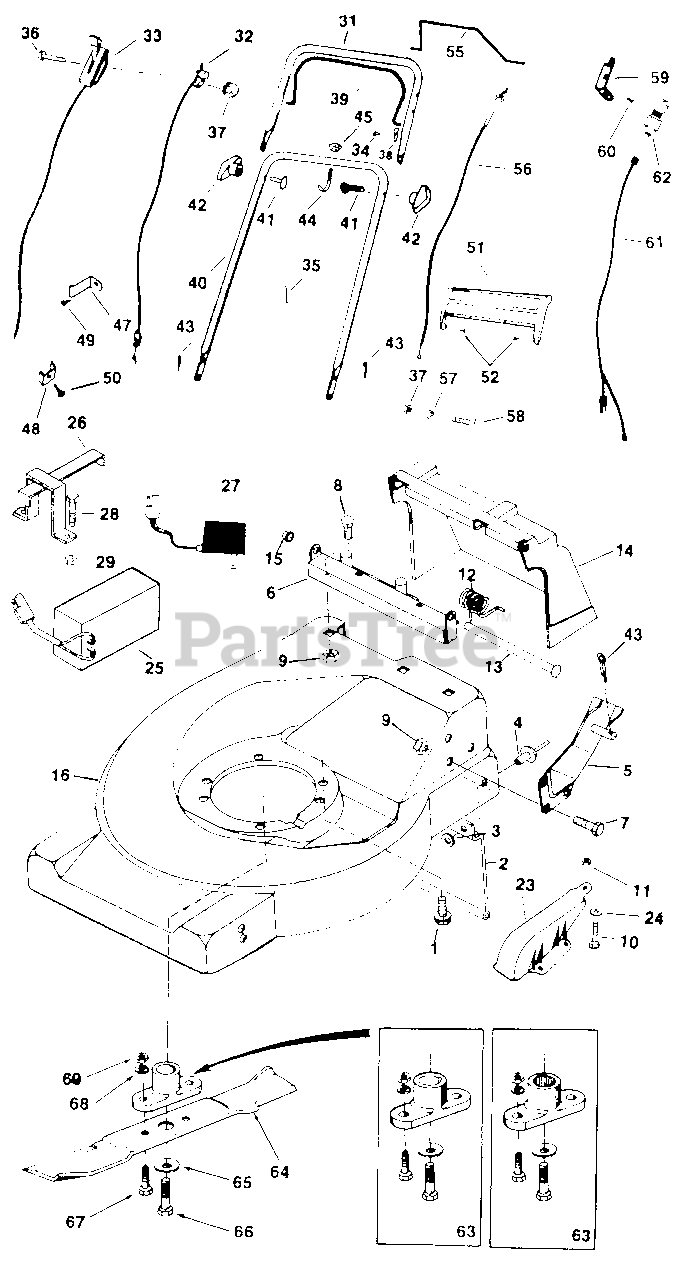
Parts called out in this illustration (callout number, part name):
1	Engine Mounting BoH
2	Trail Shield
3	Fl-Wash. 3/16"1. D.
4	Blind Rivet
5	Handle Bracket
6	Mount Bracket - Grass Catcher
7	Hex Bolt 5/16-18 x 5/8" Lg.
8	Carriage Bolt 5/16-18 x 3/4" Lg.
9	Hex Keps Nut 5/16-18 Thd.
10	Carriage Bolt 1/4-20 x 5/8" Lg.
11	Hex L-Nut 1/4-20 Thd.
12	Spring - Rear Door
13	Hinge Pin - Rear Door
15	Retainer
16	21" Deck Ass'y.
23	Belt Cover
24	Bolt Retainer
25	Battery-12V
26	Battery Bracket
27	Battery Charger
28	Hex Bolt 1/4-20 x 5/8" Lg.
29	Hex L-Nut 1/4-20 Thd.
31	UpperHandle (w/Foam Grip)
32	Brake Cable
33	Throttle Control
34	Tap Screw #10-32x 1/2"
35	Plastic Tie
36	Hex Bolt 1/4-20 x 2" Lg.
37	Hex L-Nut 1/4-20 Thd.
38	L.H. Bail Stop Bracket
39	Engine Control Lever
40	Lower Handle
41	Saddle Bolt 5/16-18 x 2" Lg.
42	Knob- Handle
43	coner Pin 1/8" x 3/4" Lg.
44	Rope Guide J-Bolt
45	Hex Keps Nut 1/4-20 Thd.
47	Guide Bracket - Cable
48	Clamp - Throttle Cable
49	Tap Screw #10 x 5/8" Lg.
50	Hex Screw #10 x 5/8" Lg.
51	Trim Panel
52	Tap Screw #10-32x 1/2"Lg.
55	Drive Control Lever
56	Drive Cable Ass'y.
57	Idler Pulley
58	Hex Bolt 1/4-20 x 7/8" Lg.
59	Switch Mounting Bracket
60	Blind Rivet
61	Wiring Harness
62	Switch & Key Ass'y.
63	Blade Adapter Kit
64	21" Blade
65	Bell-Wash. .39" I.D. x 1.14" O.D. (Keyed)
66	Hex Bolt 3/8-24 x 1-1/2 (w/Keyed Adapter)
67	Hex Bolt 3/8-24 x 1" Lg.
68	L-Wash. 3/8" I.D.
69	Hex Nut 3/8-24 Thd.
